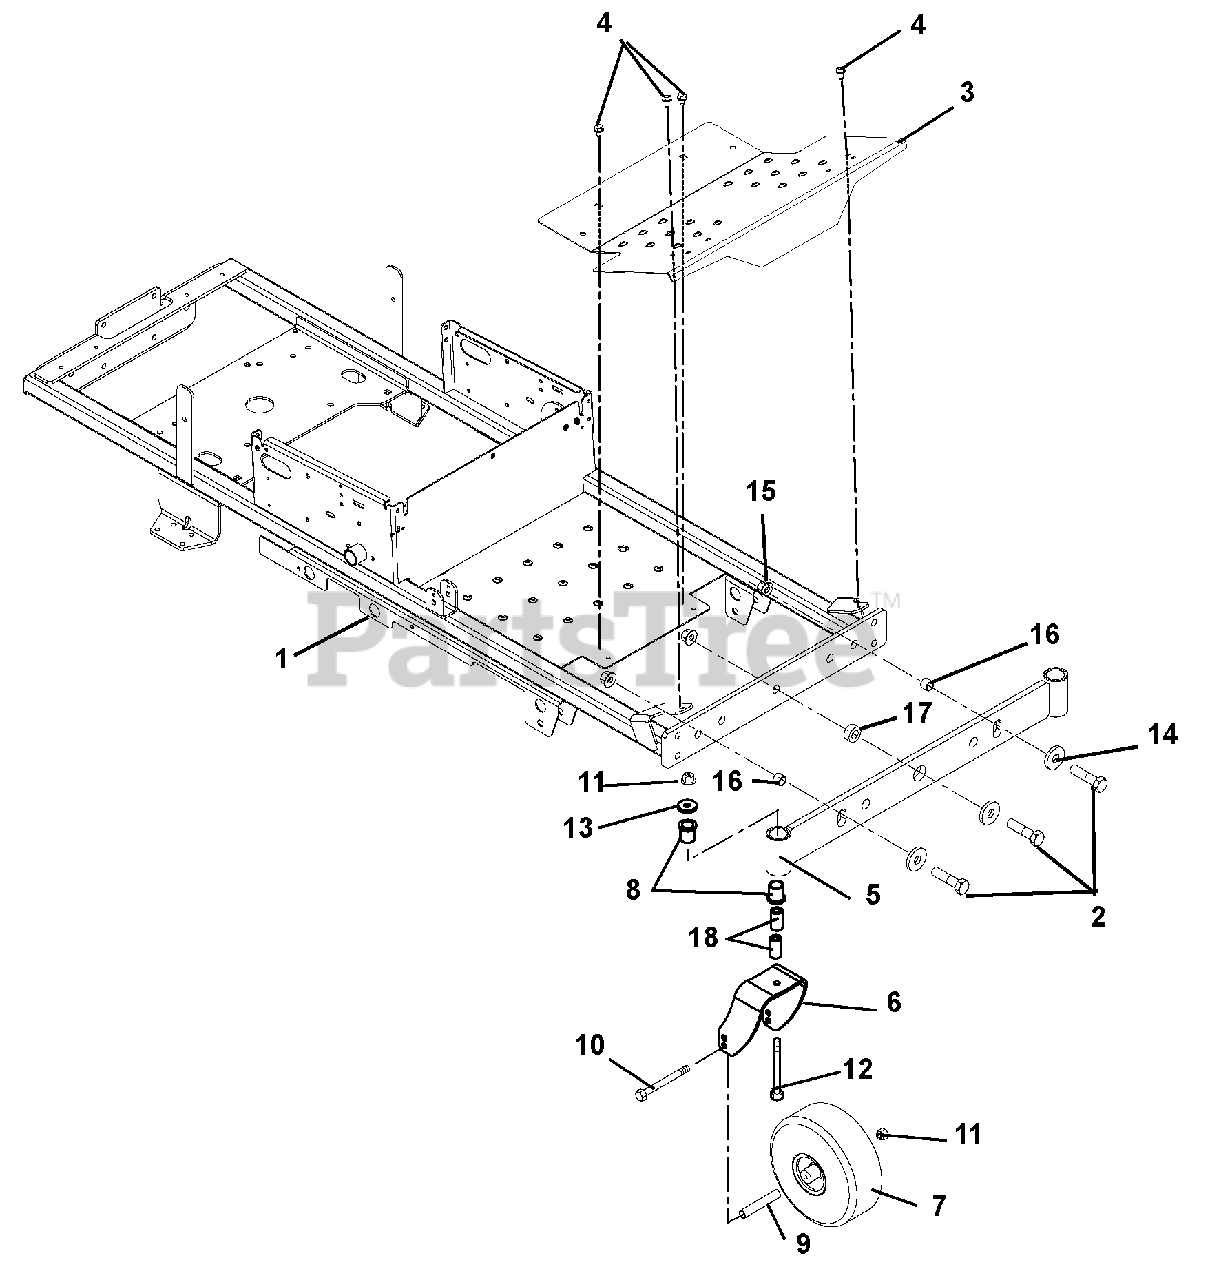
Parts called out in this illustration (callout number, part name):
1	Weldment, Frame
2	Bolt, Hex .62-11 x 2.25 Grade 8
3	Footrest
4	Screw, Tapping .31-18 x .50
5	Weldment, Front Axle
6	Fork, Caster
7	Tire, 11.0
8	Bushing, Flange 1.00 x 1.25 x 1.50 x 1.88
9	Spacer, Wheel
10	Bolt, Hex .50-13 x 6.50 Grade 5
11	Nut, .50-13 Nyloc Flange
12	Bolt, Hex .50-13 x 5.00 Grade 5
13	Washer, Flat Steel .511 x 1.441 x .125
14	Washer, Flat .640 x 1.81 x .250
15	Nut, Nyloc Flange .62-11
16	Spacer, .750 D x .558 Long
17	Bushing, Axle Pivot
18	Spacer, Caster
